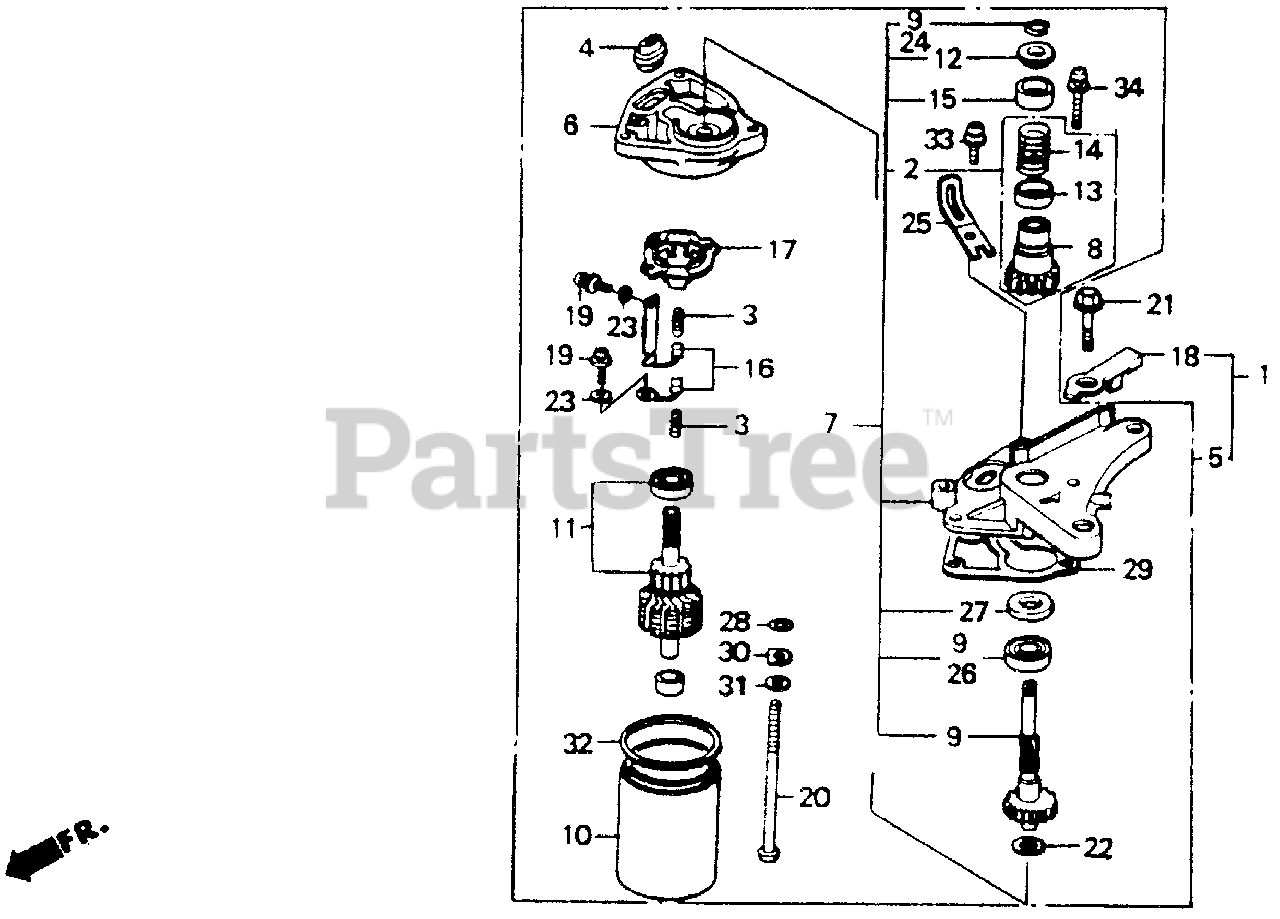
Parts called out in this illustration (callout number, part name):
1	MOTOR UNIT SET, STARTER
1	MOTOR UNIT, STARTER
2	GEAR SET, PINION
3	SPRING, BRUSH
5	MOTOR UNIT SET, STARTER
5	MOTOR UNIT, STARTER
6	BRACKET, FR.
7	COVER, GEAR
8	GEAR, PINION (16T)
9	SHAFT SET, GEAR
10	YOKE ASSY.
11	ROTOR ASSY.
12	PIECE A, STOPPER
13	PIECE B, STOPPER
14	SPRING, RETURN
15	COVER, SPRING
17	HOLDER, BRUSH
18	CLIP, WIRE
19	SCREW-WASHER (3X8)
20	BOLT, SETTING
21	BOLT, FLANGE (6X32)
22	WASHER, PINION
23	WASHER, SPECIAL
24	CIRCLIP (7.1MM)
25	CLAMP, CORD
26	SHAFT SET, GEAR
29	GASKET
30	WASHER, SPECIAL
31	WASHER, SPRING
33	SCREW-WASHER (5X16)
34	SCREW-WASHER (5X3)
